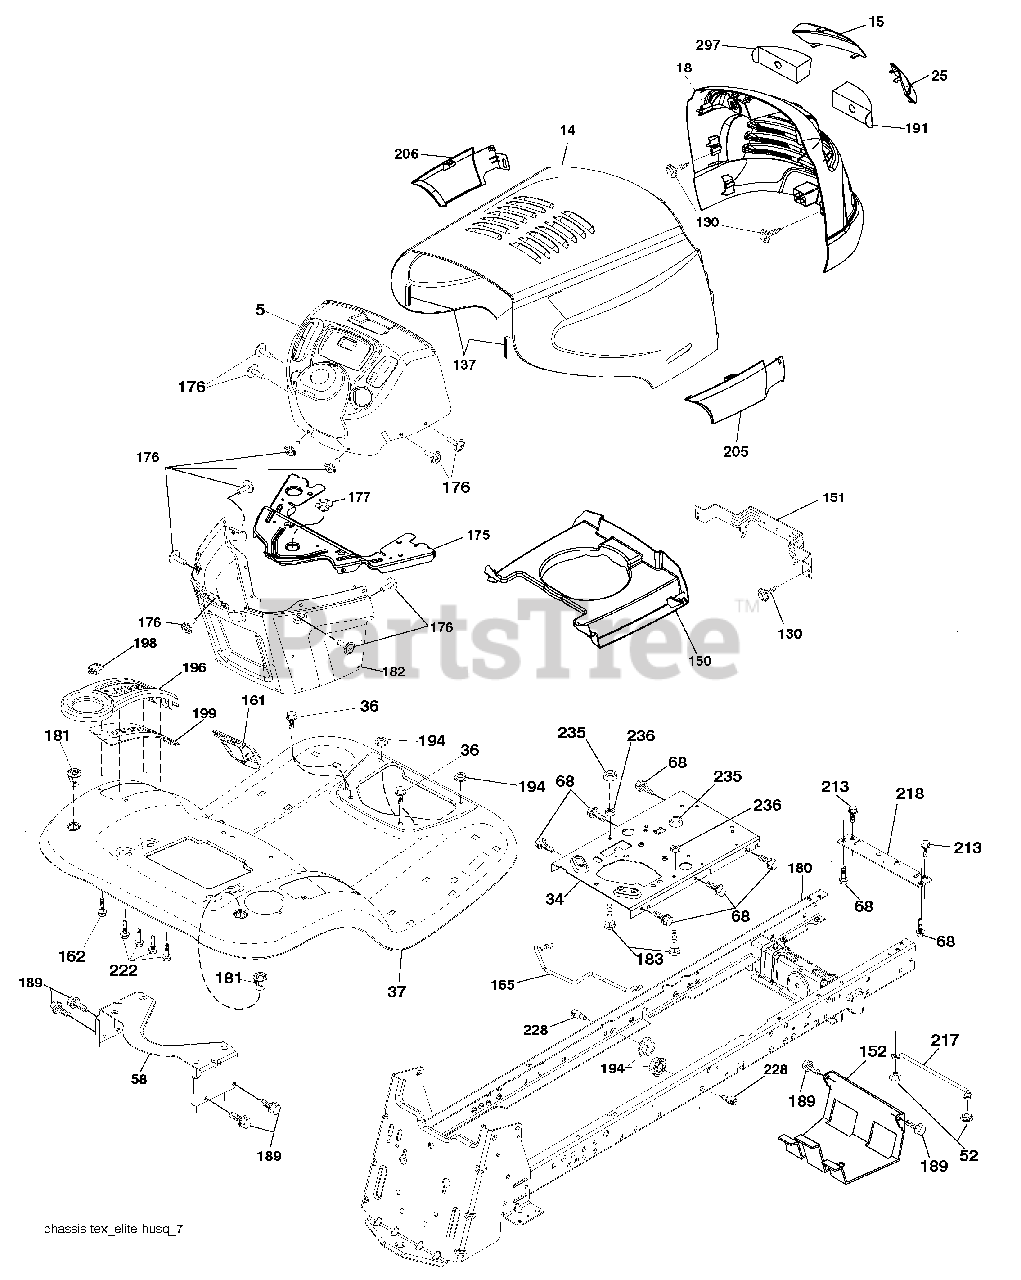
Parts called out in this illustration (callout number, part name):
5	Dash
14	Hood
15	Lens Grille LH
18	Grille
25	Lens Grille RH
34	Plate Engine
36	Screw 5/16-18 x 3/4
52	Nut Crown Lock 5/16-18
58	Fender Support Bracket
68	Screw THDROL 5/16-18 x 1/2
130	Screw #10 x 0.750 BOS Thread
137	Bumper Hood
150	Duct Heat Hood
151	Bracket Pivot
152	Shield Browning/Debris
161	Window Fuel
162	Screw Hex Wsh Hi-Lo 1/4 x 1/2 unc
165	Support Tank Rear
175	Crossmember
176	Screw 10-24 x 5/8 Wshd Qdrx
177	Bushing Steering
180	Chassis
181	Bushing Mtg. Fender Crgo.
182	Dash Lower
183	Bolt Full Thd. 5/16-18 x 1-1/4
189	Screw 5/16-18 x 3/4
191	Insert Lens Reflective RH
194	Nut Lock Hex Flange 5/16-18
196	Console Asm. Deck Lift
198	Indicator Deck Lift
199	Plate Deck Lift
213	Bolt Hex HD 5/16-18 unc x 3/4
217	Rod Pivot
218	X-Piece Hood
222	Screw Thd. Roll 1/4-20 x 5/8
228	Stud Fastener
235	Spacer Fender
236	Nut Center Lock 5/16-18 unc
297	Insert Lens Reflective LH
297	Plug Cruise Hook Phone
